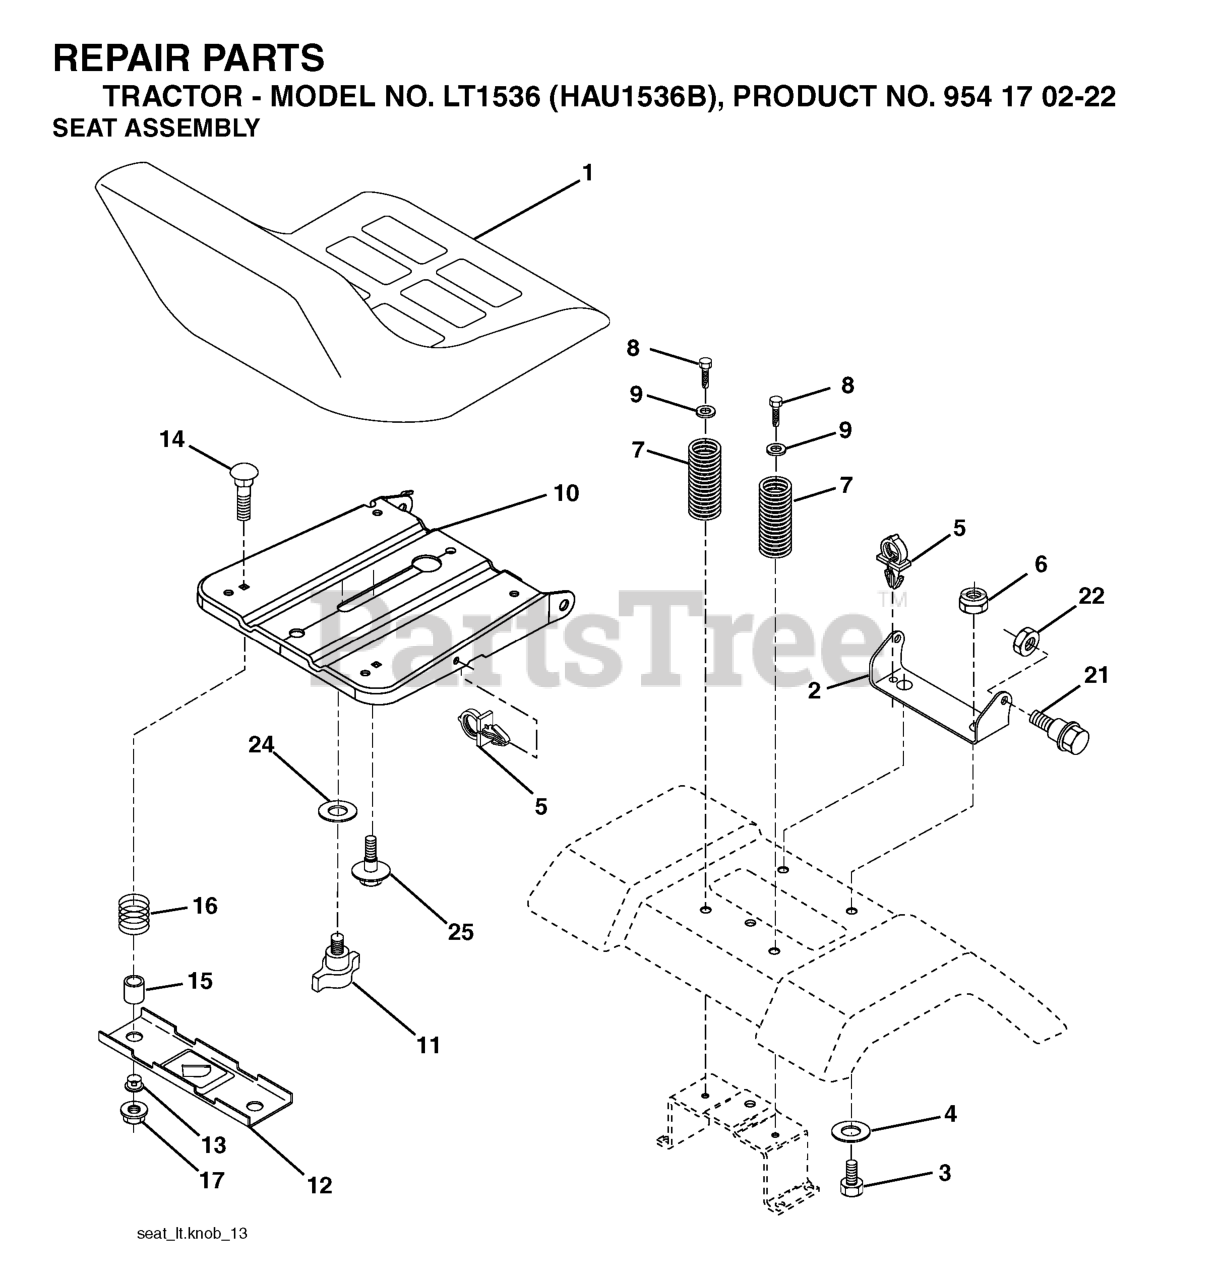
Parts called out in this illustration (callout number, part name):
1	SEAT
2	SEAT PIVOT BRKT
3	BOLT, HEX 3/8-16X1
6	NUT
7	SPRING COMPRESSION
8	SCREW 3/8-16X1
9	WASHER
10	PAN SEAT
11	KNOB.SEAT.ADJ.WINGNUT
12	BRKT SWITCH
14	BOLT.ROUND.HEAD.SQUARE.NECK
15	SPACER SPLIT 28X.96
17	NUT T
21	BOLT.SHOULDER.5/16-18
22	NUT.71038.31-18.HEX.NYLOCK
25	BOLT,SHOULD
